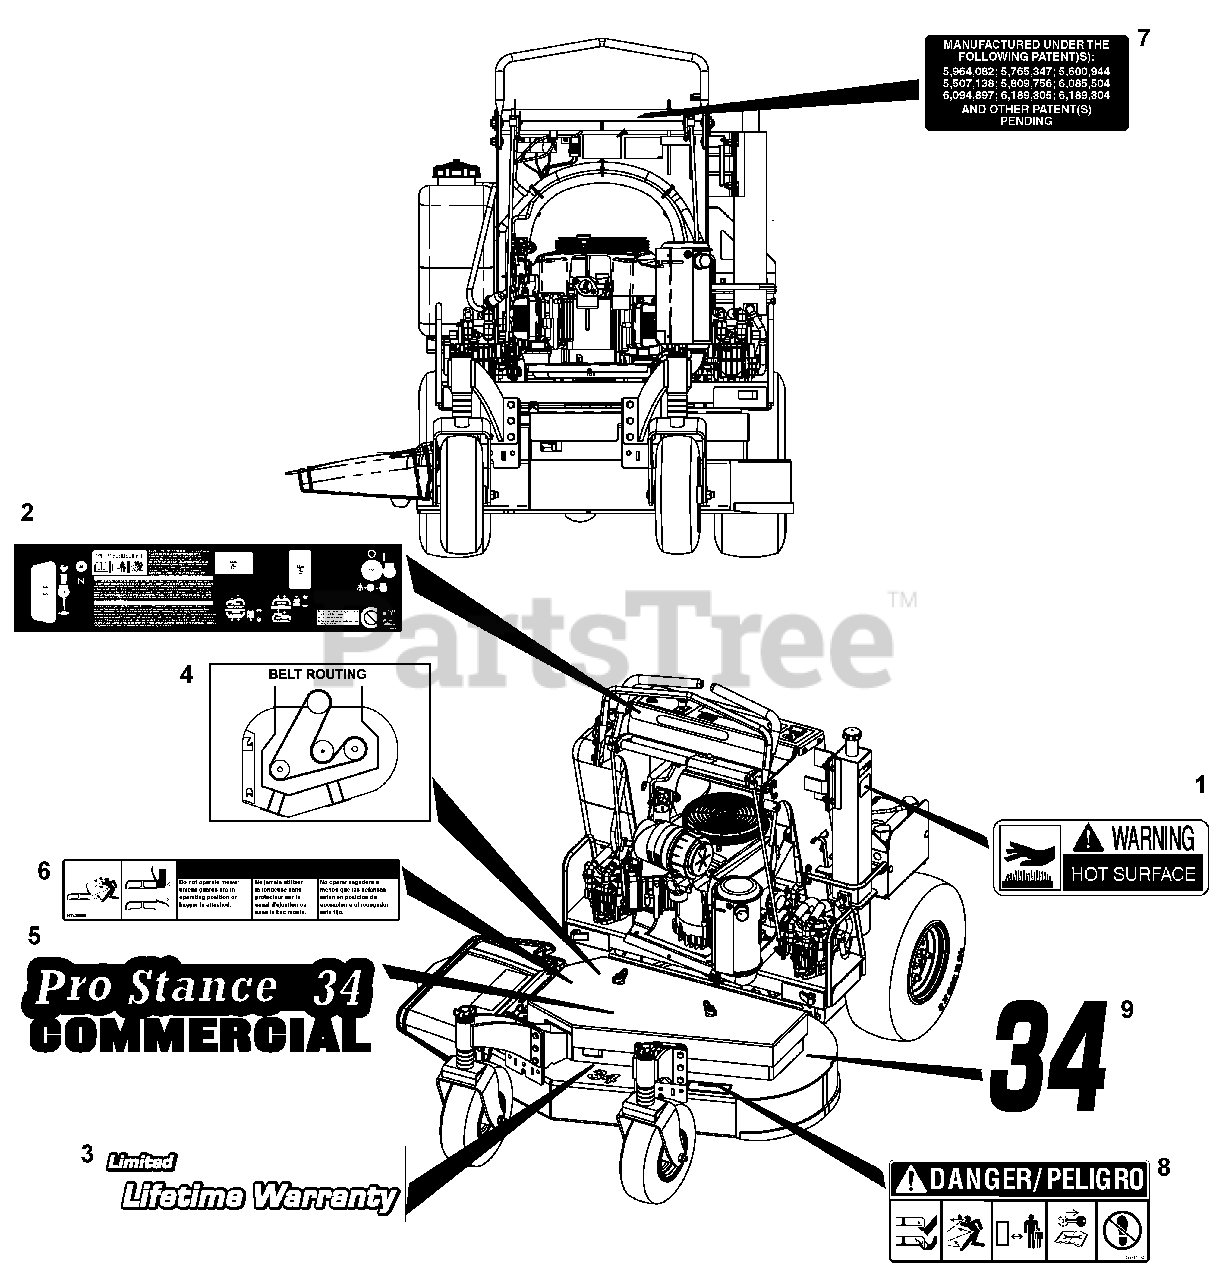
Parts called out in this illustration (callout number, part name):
1	Decal, Warning, Hot Surface
2	Decal, Console
3	Decal, Limited Lifetime Warranty
4	Decal, Belt Path
5	Decal, Pro-Stance
6	Decal, Danger - Thrown Objects
7	Decal, Patent
8	Decal, Mower Pan Head Danger
9	Decal, Deck Size 34"
